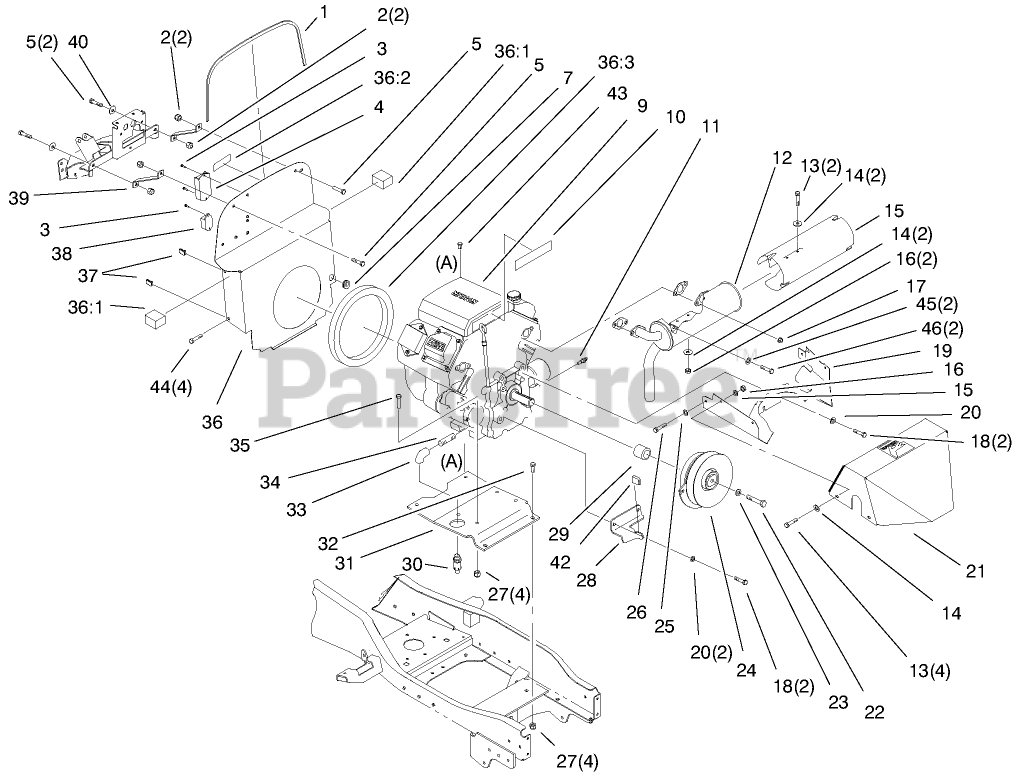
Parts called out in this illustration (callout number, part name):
1	TRIM-LOCK
1	TRIM - LOCK, BULKHEAD
2	NUT-LOCK, NI
3	SCREW
5	SCREW-HH
7	GROMMET
10	DECAL - 18 HP ENGINE
10	DECAL - 20 HP ENGINE
12	MUFFLER
13	SCREW-HH
14	WASHER-FLAT
15	REFLECTOR - HEAT
16	NUT-LOCK, CONE
18	SCREW-HH
19	SHRD-MUFFLER
20	WASHER-LOCK
21	SHROUD-MUFFLER
22	SCREW-HH
23	WASHER-FLAT
24	CLUTCH-PTO
25	WASHER-LOCK
26	SCREW-HH
27	NUT-LOCK, NI
28	CLUTCH-STOP
29	SPACER-CLUTCH
30	VALVE-DRAIN, OIL
32	SCREW-HH
33	ELBOW-90 DEGEE
34	NIPPLE
35	SCREW-HH
36	Bulkhead ASM (Only On: 73541)
36:1	SEAL-FOAM, SIDE
36:2	DECAL-WARNING
36:2	DECAL - WARNING
36:3	SEAL-FOAM
38	MODULE - CRUISE
39	BRACKET-BULKHEAD
40	WASHER-FLAT
42	BUMPER
43	SCREW-THD
44	SCREW-HH
45	WASHER-LOCK
46	SCREW-HHF
